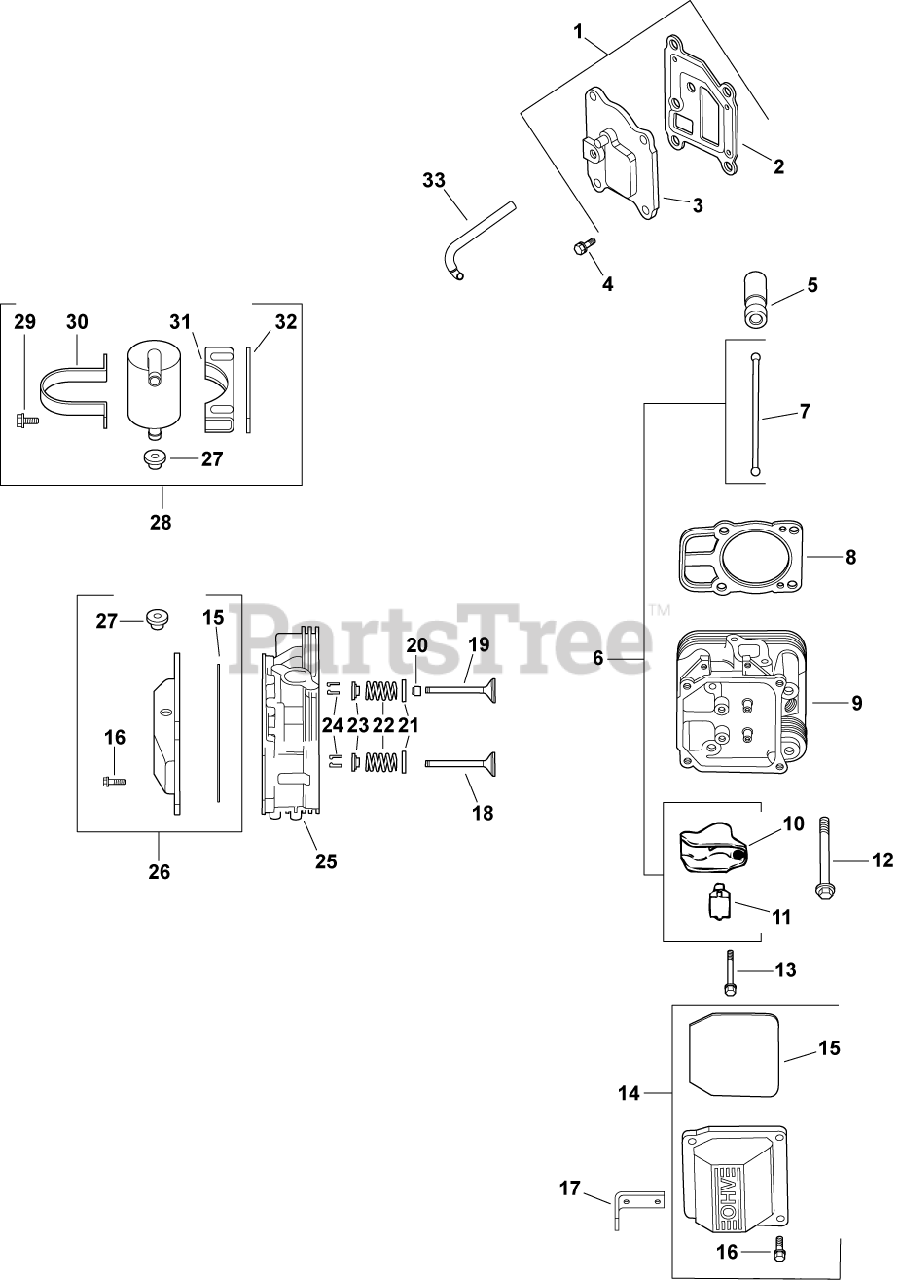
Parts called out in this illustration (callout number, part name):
1	KIT, BREATHER COVER W/GASKET
2	GASKET, BREATHER-USE 24 041 67-S
3	COVER, BREATHER -USE 24 096 125-S
4	SCREW,FLG THD FRM M6X1.0X20-(#25086396S)
5	LIFTER, HYDRAULIC VALVE-USE 25 351 10-S
6	KIT, VALVE TRAIN
7	ROD, PUSH
8	KIT, GSKT CYL HD (C22-23 674CC)
9	HEAD, ASSEM CYLINDER #2 -USE 24 318 116-
10	PIVOT, ROCKER ARM
11	ARM, ROCKER
12	SCREW, FLG M6X1.0X34
13	SCREW - DISCONTINUED
14	KIT, VALVE COVER-PLAIN
15	O-RING (YELLOW) -USE 24 153 30-S
16	SCREW, FLG M6X1.0X30
17	STRAP, LIFTING-USE 25 445 03-S
18	VALVE, EXHAUST (STD) - USE 32 016 01-S
19	VALVE, INTAKE (STD)
20	SEAL, VALVE STEM - (#2503214S)
21	RETAINER, SPRING
22	SPRING, VALVE
23	RETAINER, VALVE SPRING - USE 25 173 28-S
24	KIT, RETAINER
25	HEAD, ASSEM CYLINDER #1 -USE 24 318 108-
26	KIT, VALVE COVER
27	GROMMET, RUBBER
28	KIT, BREATHR SEPARATR-(#24755241S)
29	SCREW,FLG THD FRM M5X0.8X16-(#25086398S)
30	STRAP, BREATHER - USE 24 755 241-S
31	BRACKET, BREATHER SEPARATOR
32	SPACER
33	HOSE, FLEXIBLE
2401602-S	VALVE, EXHAUST (.25)
2401702-S	VALVE, INTAKE (.25)
